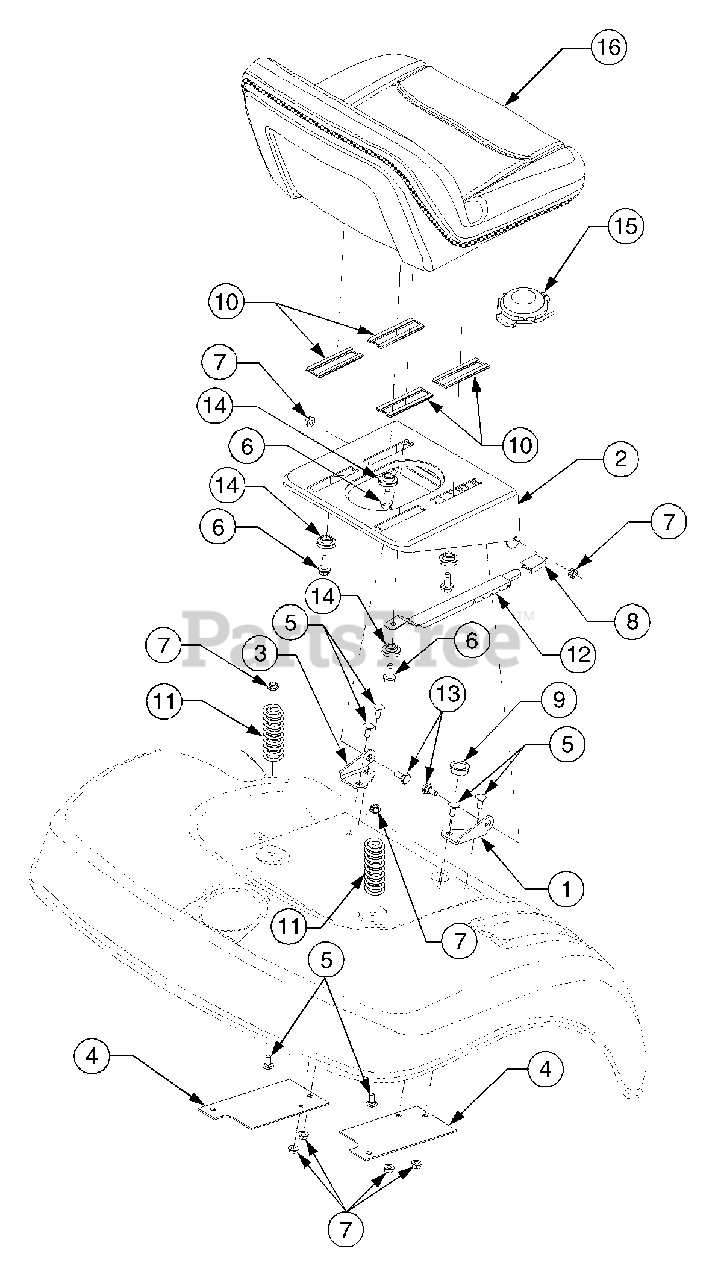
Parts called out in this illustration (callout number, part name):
6	Screw, Hex Wash. Hd., 5/16-18 x .75 GR5
7	Nut, Hex Flange Lock, 5/16-18
8	Knob, Seat Adjuster
9	Bushing, Snap
10	Slide, Seat
11	Spring, Comp, 1.9 OD x 2.4
12	Index Spring, Seat Adjuster
13	Bolt, Shoulder
14	Spacer, Shoulder
15	Switch, Seat
16	Seat, Mid Back
